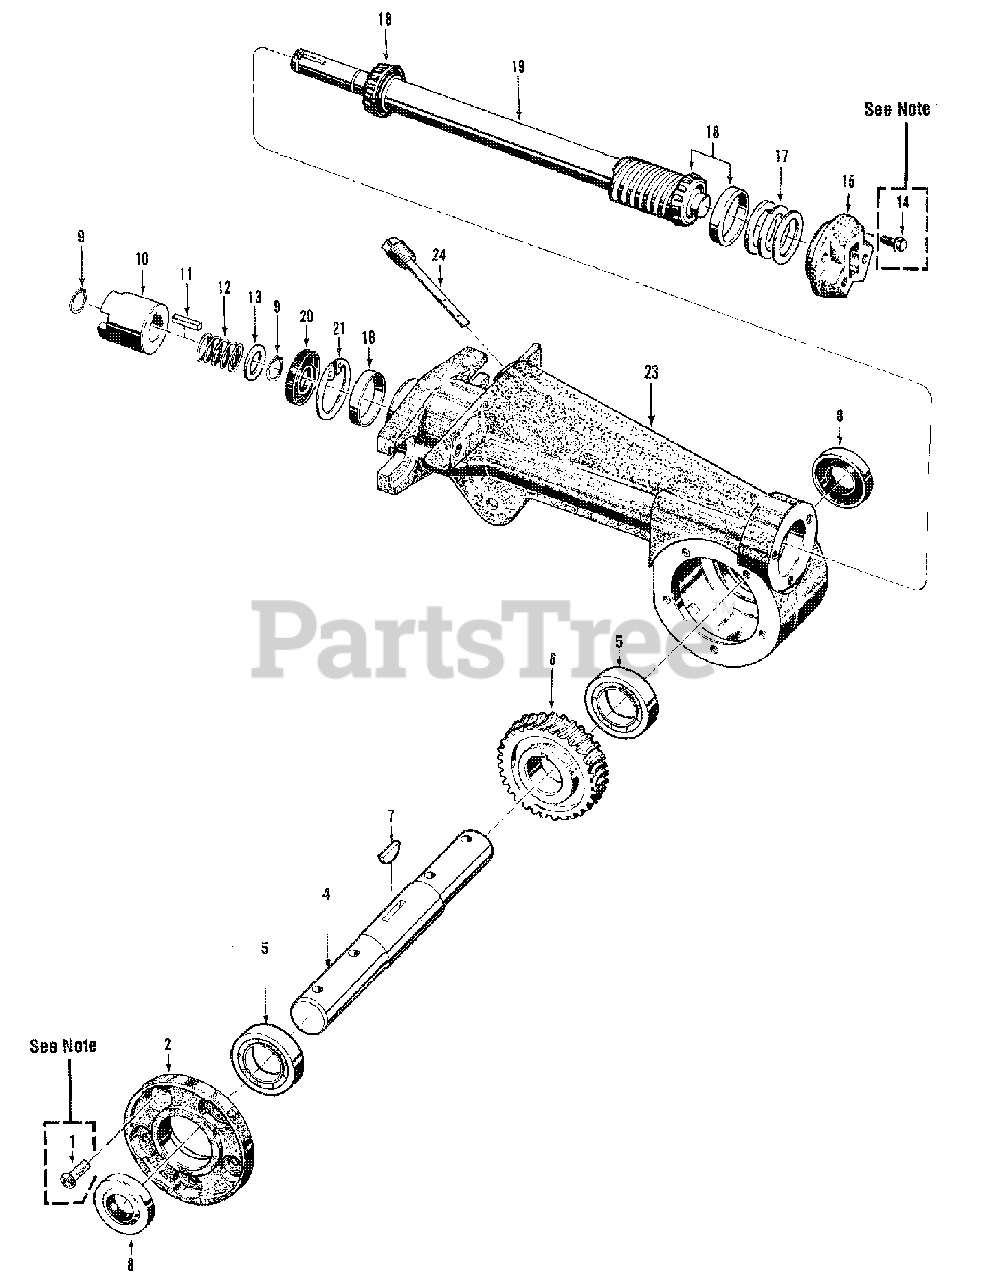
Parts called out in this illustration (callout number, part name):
1	Screw-self-sealing,1/4"-20 x 5/8"
2	Cover-tiller housing
4	Shaft-tiller tine
5	Ball Bearing
6	Worm Gear-bronze, tiller tine shaft
7	Key-tiller tine shaft, woodrudd key
8	Seal-oil, tiller tine shaft
9	Retaining Ring-external
10	Dog Clutch-tiller drive shaft
11	Key-3/16" x 1"
12	Spring-dog clutch
13	Shim-dog clutch, 1/16"(.62")thick
14	Screw-self-sealing,1/4"-20 x 7/8"
15	Cap-rear bearing
17	Shim-front bearing cap, .010"thick
17	Shim-same as above, .030" thick
17	Shim-same as above, .005" thick
17	Shim-same as above, .062" thick
18	Bearing & Race(Incl. One bearing GW-9400 and One cup (race) GW-9401)
19	Shaft-main tiller drive
20	Seal-oil, drive shaft, front
21	Retaining Ring-Internal
23	Housing-tiller attachment.
24	Dipstick-oil, tiller attachment
